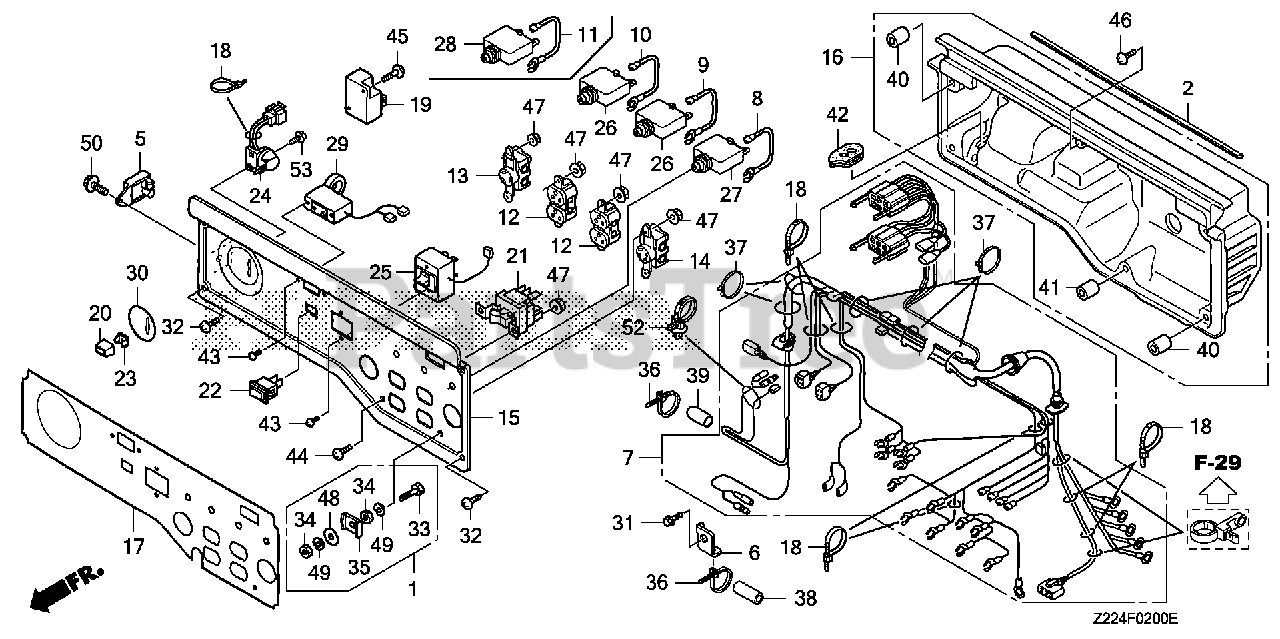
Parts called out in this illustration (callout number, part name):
1	TERMINAL SET, GROUND
2	RUBBER, CONTROL
6	BRACKET, WIRE HARNESS CLIP (A)
7	WIRE HARNESS ASSY., CONTROL
8	WIRE, TERMINAL (A)
9	WIRE, TERMINAL (B)
10	WIRE, TERMINAL (C)
11	WIRE, TERMINAL (D)
12	RECEPTACLE ASSY. (125V-20A) (MATSUSHITA)
12	RECEPTACLE (20A/125V) (CONFIRM RECEPTACLE AS NON-GCFI. IF GCFI, TRY #42.)
13	RECEPTACLE (30A-125V)
13	RECEPTACLE (3-PRONG) (30A/125V)
14	RECEPTACLE (30A/125-250V)
14	RECEPTACLE (30A-125/250V)
15	PANEL, CONTROL *NH105* (MAT BLACK)
16	CASE, CONTROL PANEL *R280* (POWER RED)
17	MARK, PANEL
18	TIE, CABLE (C)
19	CONTROL UNIT, IDLE
20	KNOB, ENGINE SWITCH
21	SWITCH ASSY., VOLT CHANGE
22	SWITCH ASSY., IDLE CONTROL
23	BUSH, CONTROL KNOB
24	SWITCH ASSY., ENGINE STOP
25	BREAKER, CIRCUIT (25A)
26	PROTECTOR, CIRCUIT (20A)
27	PROTECTOR, CIRCUIT (30A)
28	PROTECTOR, CIRCUIT (30A)
29	RELAY ASSY. (GFCI)
30	MARK, ENGINE SWITCH
31	BOLT, FLANGE (6X12) (CT200)
32	SCREW, TRUSS (6X18)
33	BOLT, HEX. (6X28)
34	NUT, HEX. (6MM)
35	RETAINER (6MM)
36	STRAP, CABLE (105MM) *NH1* (Honda Code 1685536). (BLACK)
37	TIE, CABLE (NATURAL 225X5.0)
38	TUBE, CORD
39	TUBE (22X60)
40	COLLAR, CONTROL CASE
41	COLLAR, CONTROL CASE
42	GROMMET, TUBE
43	SCREW, PAN (4X6)
44	SCREW, PAN (5X18)
45	SCREW-WASHER (5X14)
46	SCREW, TAPPING (4X16) (NOT AVAILABLE)
47	NUT, FLANGE (4MM)
48	WASHER, PLAIN (6MM)
49	WASHER, SPRING (6MM)
50	BOLT, FLANGE (6X12)
53	SCREW, PAN (4X8)
